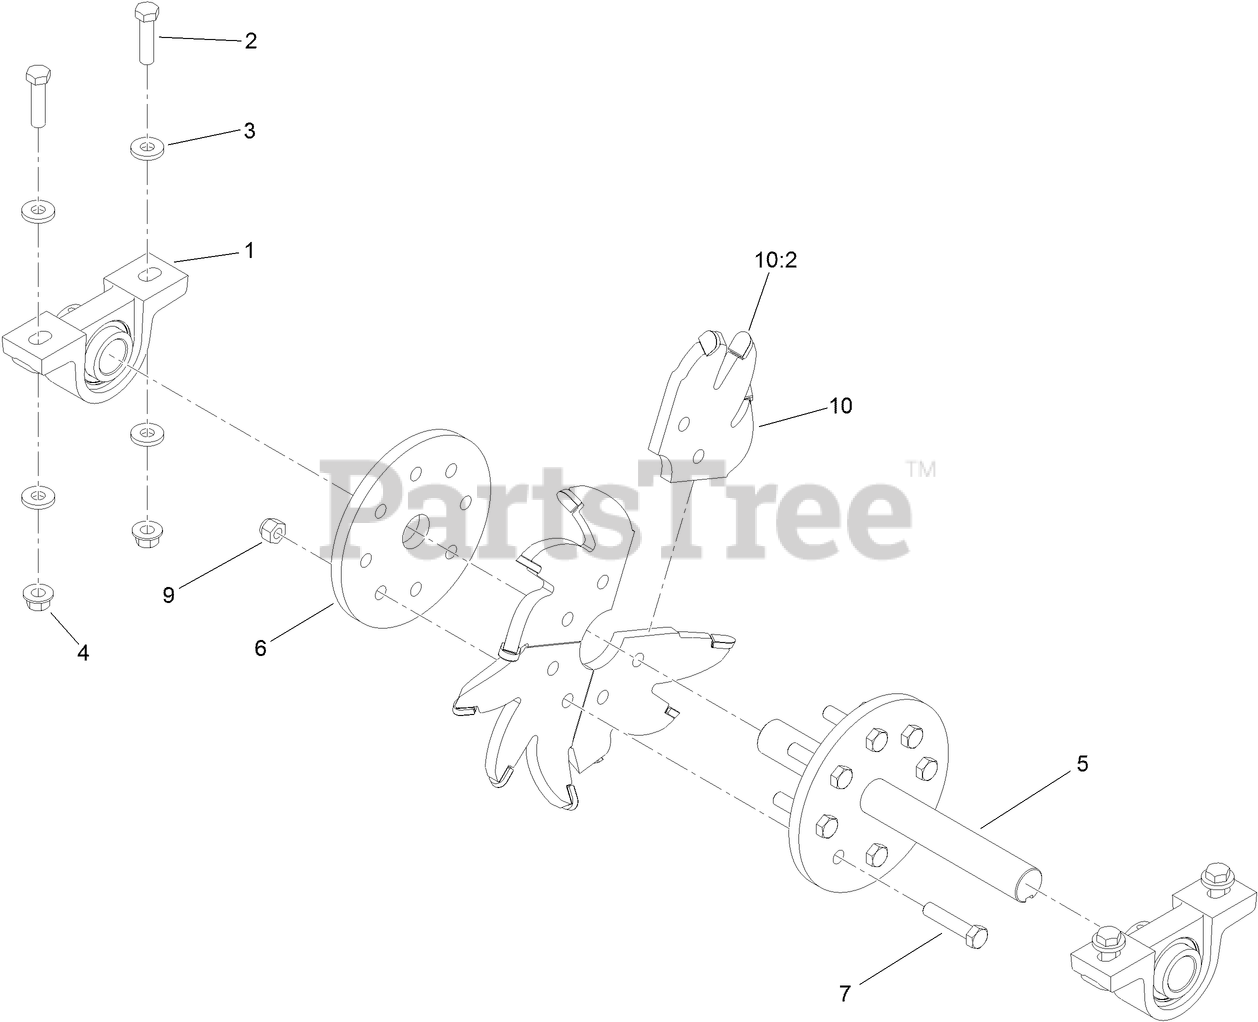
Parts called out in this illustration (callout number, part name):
1	BEARING ASM
2	SCREW-HH
3	SPACER
4	NUT-LOCK
5	BLADE SHAFT ASM
6	FLANGE-SHAFT
7	SCREW-HH
9	NUT-LOCK, NI
10	BLADE-GRINDER
10:2	TIP-CARBIDE
